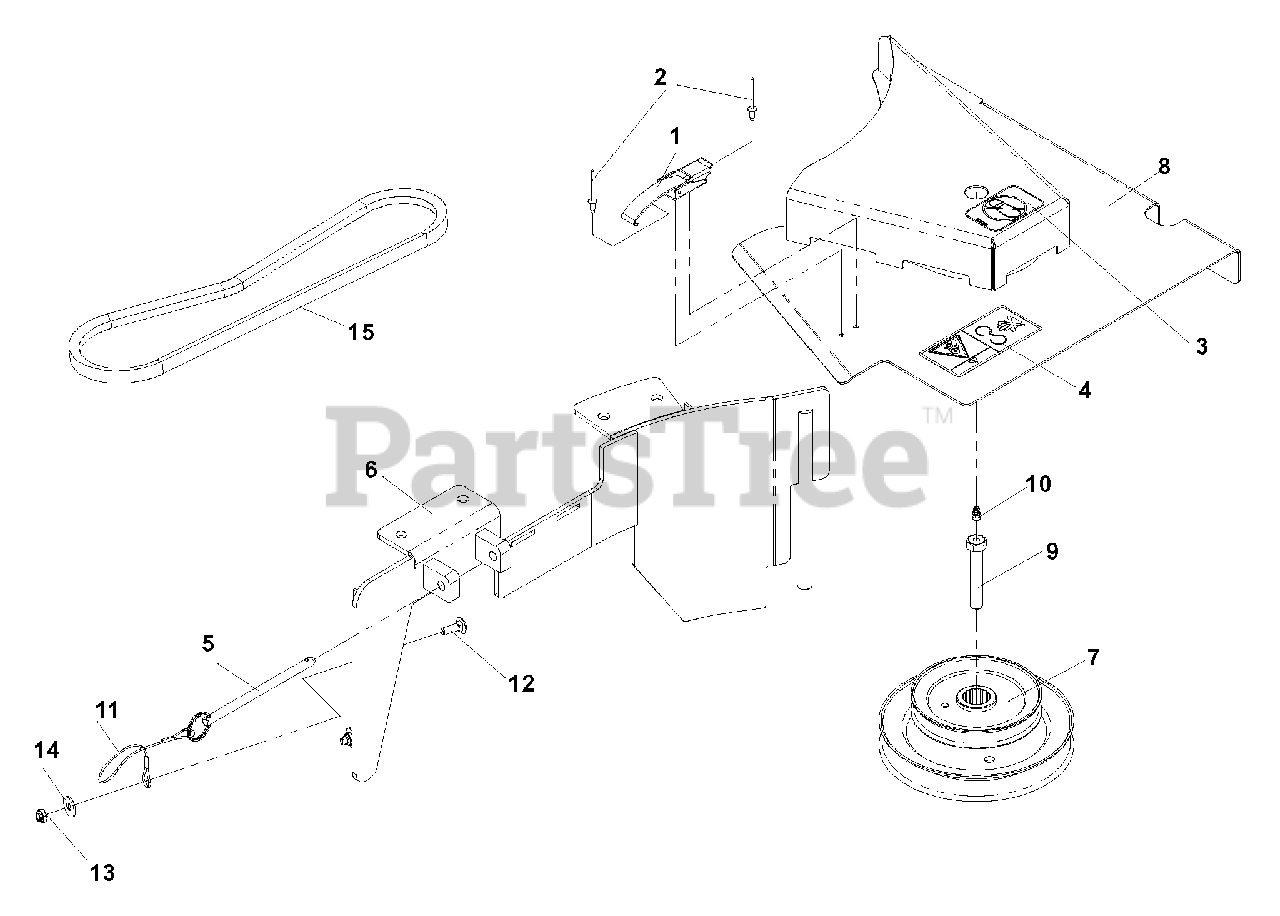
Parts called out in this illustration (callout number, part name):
1	DRAW LATCH
2	RIVET, BLIND, DOME
3	DECAL, NO STEP
4	DECAL, BELT DRIVES
6	BLOWER DECK PLATE, 61
7	PULLEY, STACKED DBL, 61
8	BELT SHIELD W/DECALS
9	HCS, 7/16 -20 x 2 1/2, GR8
10	ZERK
12	RHSNB, 1/4 -20 x 3/4, GR2
13	WASHER, 1/4
14	NUT, 1/4C, THIN NYLOC
